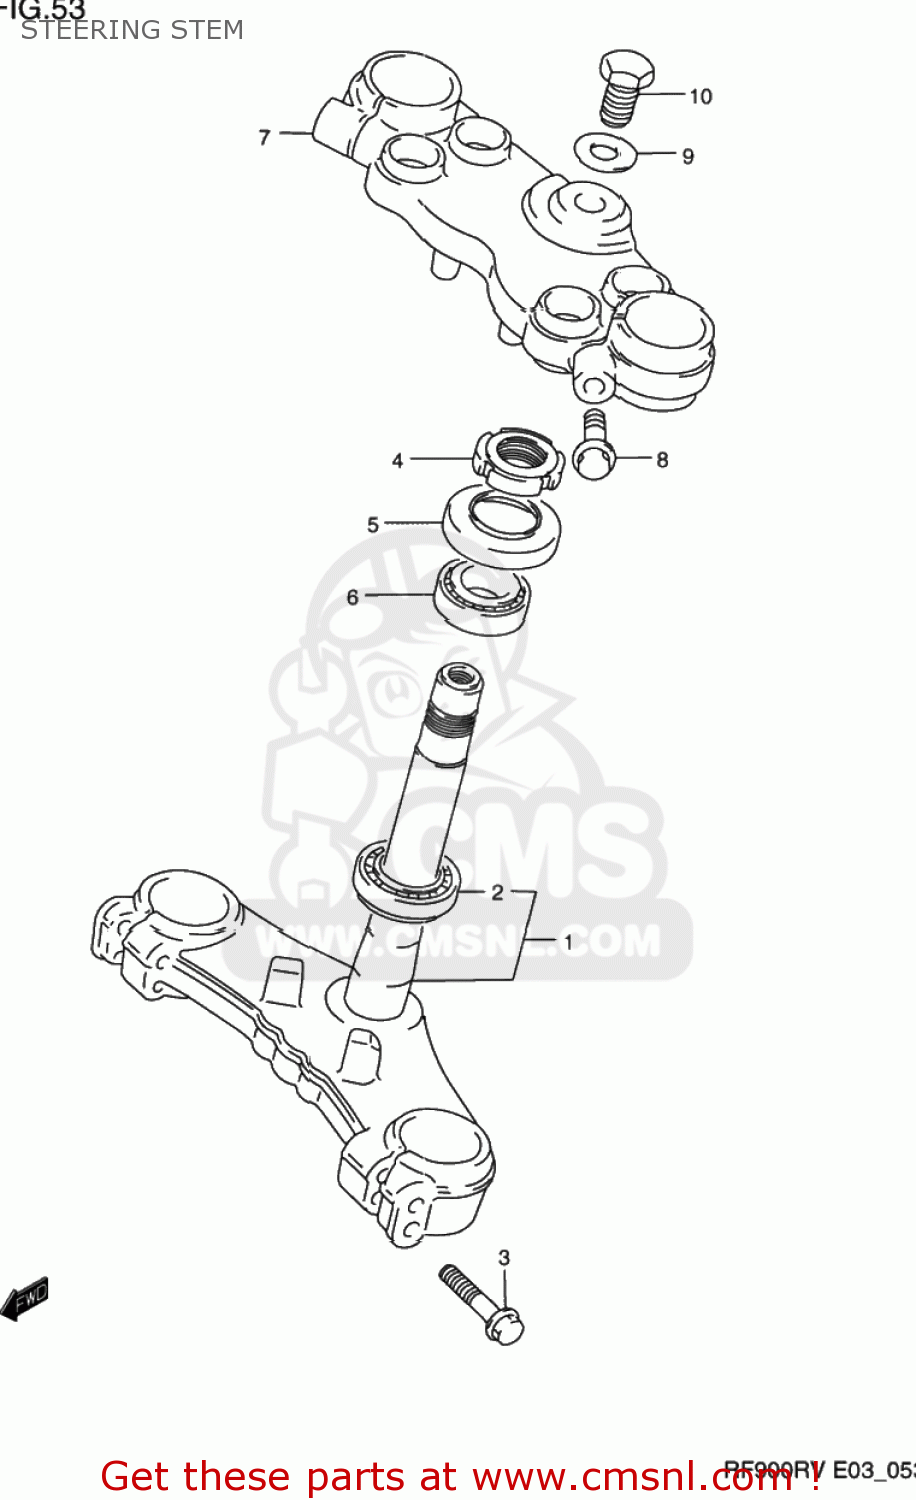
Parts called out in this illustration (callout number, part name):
1	STEM,STEERING
2	BEARING(30X55X17)
3	BOLT
4	NUT,STEERING STEM(25X44X10)
5	SEAL,STEERING UPR DUST
6	BEARING(25X47X15)
7	HEAD,STEERING STEM
8	BOLT
9	WASHER,STEERING STEM
10	BOLT,STEERING STEM HEAD
